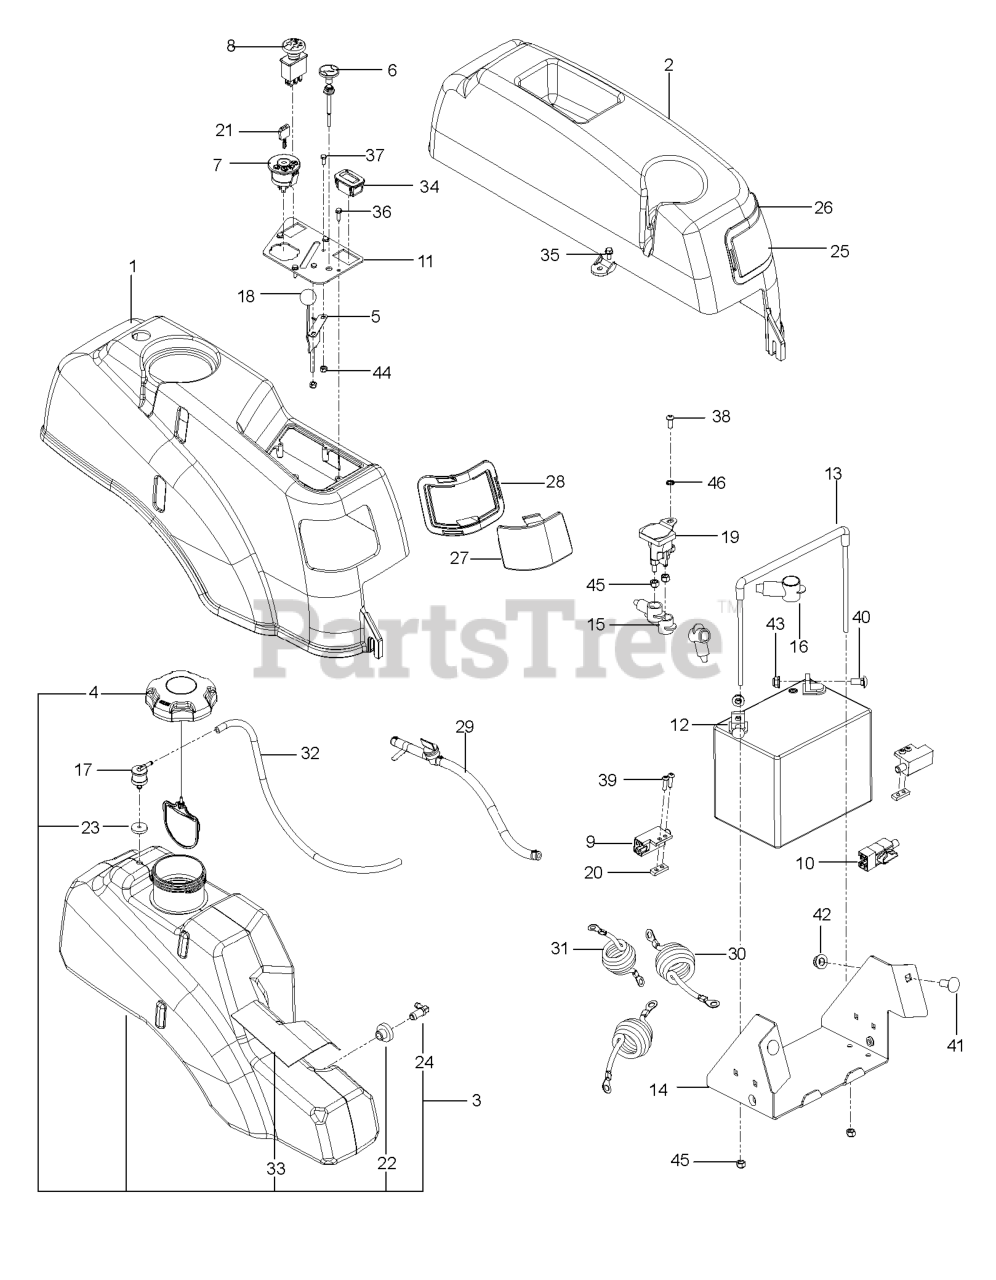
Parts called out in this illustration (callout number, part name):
1	FENDER RT, GRAY
2	FENDER, LT
3	TANK.FUEL.ASSEMBLY.LARGE
4	CAP, FUEL
5	THROTTLE CONTROL W/BALL KNOB
6	CHOKE CONTROL CABLE 57"
7	RP IGNITION SWITCH
8	RP SWITCH.PTO.8.TERMINAL.RED
9	SWITCH INTERLOCKT
10	SWITCH.INTRLCK.CLUTCH.
11	CONTROL PLATE RZ STD X431
12	BATTERY, 12 V 330 AMP
13	BATTERY TIE DOWN ASSEMBLY
14	BOX, BATTERY, BLACK
15	TERMINAL COVER-SM
17	VALVE.FUEL.CHECK
18	KNOB.ROUND.BALL.BLACK
19	SOLENOID.W/BRASS.PLUNGER
20	TAPPED PLATE
21	KEY MLD GEN DELTA
22	RUBBER GROMMET
23	GROMMET, CHECK VALVE
24	STEM, FUEL TANK
25	LENS, COLORED LEFT
26	LEFT HEADLIGHT RIM GREY
27	LENS, COLORED RIGHT
28	RT HEADLIGHT RIM GREY
29	FUEL LINE ASSY
30	BATTERY CABLE, NEGATIVE
31	CABLE POSITIVE, LONG
32	HOSE.3/16"VAPOR.27"
33	SHIELD, HEAT
34	GUAGE.SRVCMNDR.HRMTR.
35	BOLT 1/4-20 X 1/2 HWST
36	SCR #10-12X3/4 HEX WAS HD ZD
37	HCS #10-24 X 1/2
38	SCR 1/4-20 X 5/8 BTN SKT HD ZD
39	SCR #10-24 X .75 SKT HD BLK
40	BOLT 5/16C X 3/4" CARRIAGE
41	RHSNB 3/8C X 1
42	NUT 3/8-16 HEX FLG NYLOC ZD
43	5/16-18 NYLOC FLANGE NUT
44	NUT 10-24 NYLOC
45	NUT.1/4-20.HEX.NYLOC.ZD
46	WASHER 1/4 INT TOOTH
